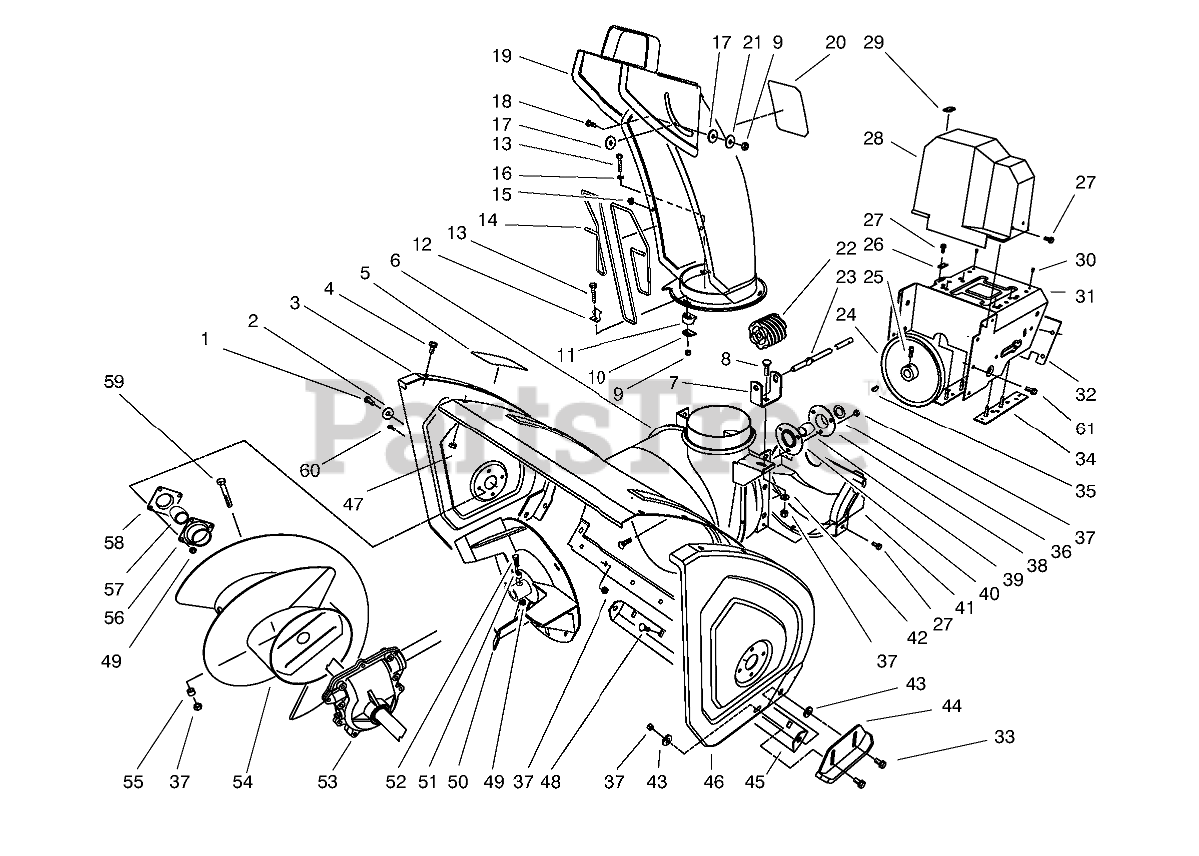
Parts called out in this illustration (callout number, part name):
1	SCREW-HH
2	WASHER
3	Plate-Side
4	SCREW-HHF
5	DECAL-WARNING, AUGER
6	Housing-24 Inch
7	BRACKET-WORM, CHUTE
8	BOLT-CARR
9	NUT-LOCK, NI
10	PLATE-RETAINER, CHUTE
11	RETAINER-CHUTE
12	CLIP-GUARD, CHUTE
13	SCREW-HSH
14	GUARD-CHUTE
15	NUT-PUSH
16	WASHER-FLAT
17	WASHER-PLASTIC
19	Assembly
20	DECAL-DANGER (only on: 38078)
21	WASHER-FLAT
22	GEAR-WORM
23	ROD-CHUTE, LOWER
24	PULLEY-IMPELLER
25	SCREW-SET, SQH
26	RETAINER-CABLE
27	SCREW-HWH
28	COVER-BELT, UPPER
29	COVER-CABLE
30	RIVET-POP
31	Frame-Engine
32	Cover-Frame, Engine
33	SCREW-HHF
34	LH FRAME PLATE ASM
35	KEY-WOODRUFF
36	WASHER-THRUST
37	NUT-LOCK, NI
38	FLANGE-CUP, BEARING
39	BEARING-BALL
40	FLANGE-CUP, BEARING
41	COVER-BELT, LOWER
42	WASHER-PLAIN
43	WASHER
44	Skid
45	Blade-Scraper
46	Plate-Side
47	NUT-LOCK, NI
48	SCREW-CARR
49	NUT-LOCK, NI
50	Impeller
51	SPACER
52	SCREW-HHF
53	AUGER GEARCASE ASM
54	Auger-RH
55	SPACER-HUB, AUGER
56	BEARING-FLANGE, FRONT
57	BEARING
58	BEARING-FLANGE, REAR
59	SCREW-HH
60	SCREW-HH
61	SCREW-HWHTF
